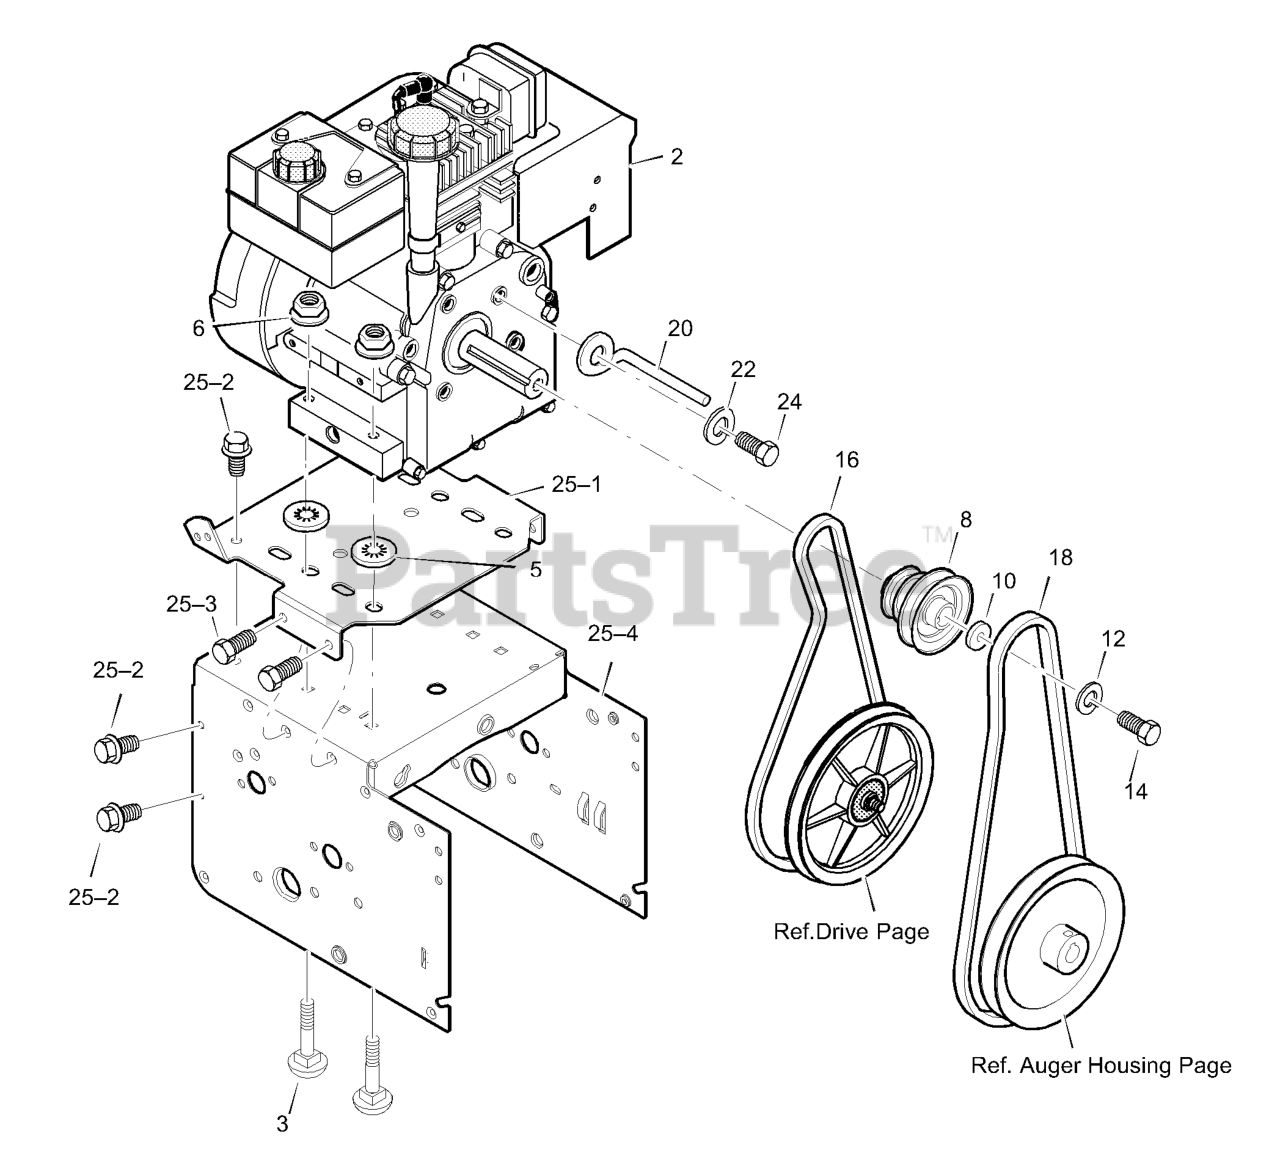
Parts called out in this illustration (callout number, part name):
2	ENGINE
3	BOLT, CARRIAGE 5/16-18
5	RETAINER, PUSH
6	NUT, HEXWDFLLK 5/16-18
8	PULLEY, ENGINE
10	WASHER
12	WASHER,HVSPTLK .38ID
14	SCREW, 3/8-24 x 1.00
16	BELT, V 3L 33.13LG
18	BELT, V 4L35.6 LG
20	GUIDE, BELT
22	WASHER, SPTLK .31X.58X.08
24	SCREW, 5/16-24 x 0.75
25-1	PLATE, ENGINE MOUNT
25-2	SCREW, TAP 1/4-20 X .63
25-3	SCREW, TAP 5/16-18 X .50
25-4	FRAME, MOTOR BOX
